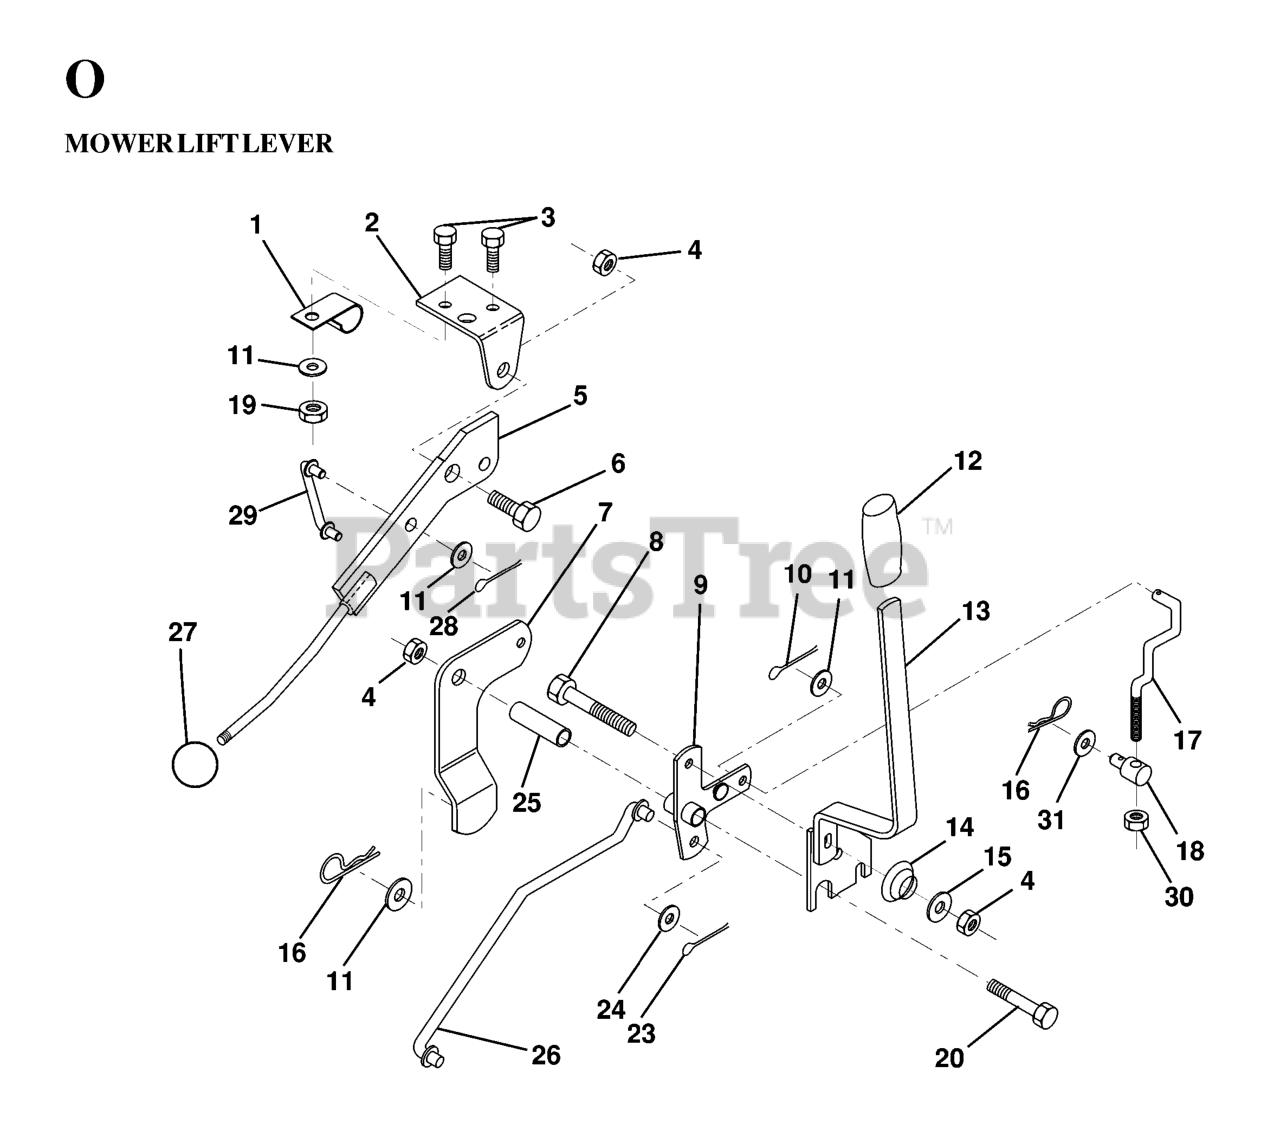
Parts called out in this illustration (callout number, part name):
1	CLIP,INSULATOR
2	BRKT CLUTCH
3	BOLT
5	CLUTCH LEVER
6	BOLT, SHOULDER LT
7	ASSEMBLY MOWER CLUTCH ARM
9	BELLCRANK,LIFT
10	COTTER PIN
11	WASHER
12	HANDLE GRIP
13	LIFT HANDLE ASSY
14	SPRING COMPRESSIO
15	WASHER T
16	SPRING TI
17	LINK LIFT FRT
18	TRUNNION.ADJUSTABLE.3/8-16
19	NUT.CROWNLOCK.1/4
23	PIN COTTER
24	WASHER GT
25	TUBE SPACER
27	KNOB T (3/8 HOLE)
28	COTTER PIN
29	LINK MOWER CLUTCH
30	NUT
31	WASHER
